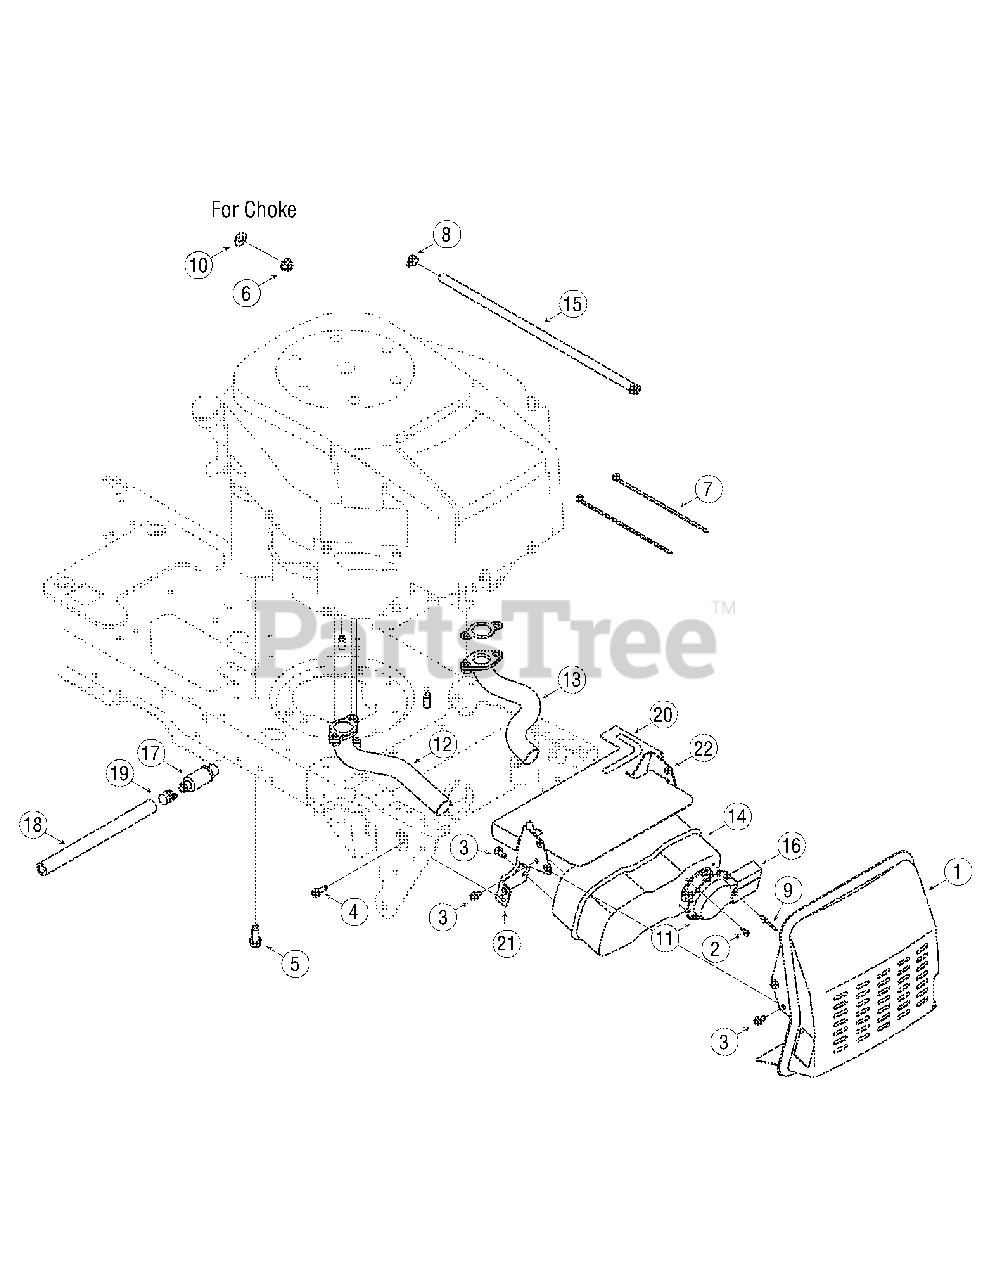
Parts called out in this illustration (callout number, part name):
2	AB Screw #8-18 x.500
3	TT Screw 1/4-20 x.500
4	TT Screw 1/4-20 x.750
5	TT Sems Screw 3/8-16 x 1
6	Flange Lock Nut 3/8-16
7	Cable Tie
8	Hose Clamp
10	Flat Washer.406 x.875 x.059
11	Muffler Deflector
12	Exhaust Pipe RH
13	Exhaust Pipe LH
14	Dual Inlet Muffler
16	Muffler Deflector, Long
17	Oil Drain
18	Oil Drain Hose Extension
19	Oil Drain Cap
